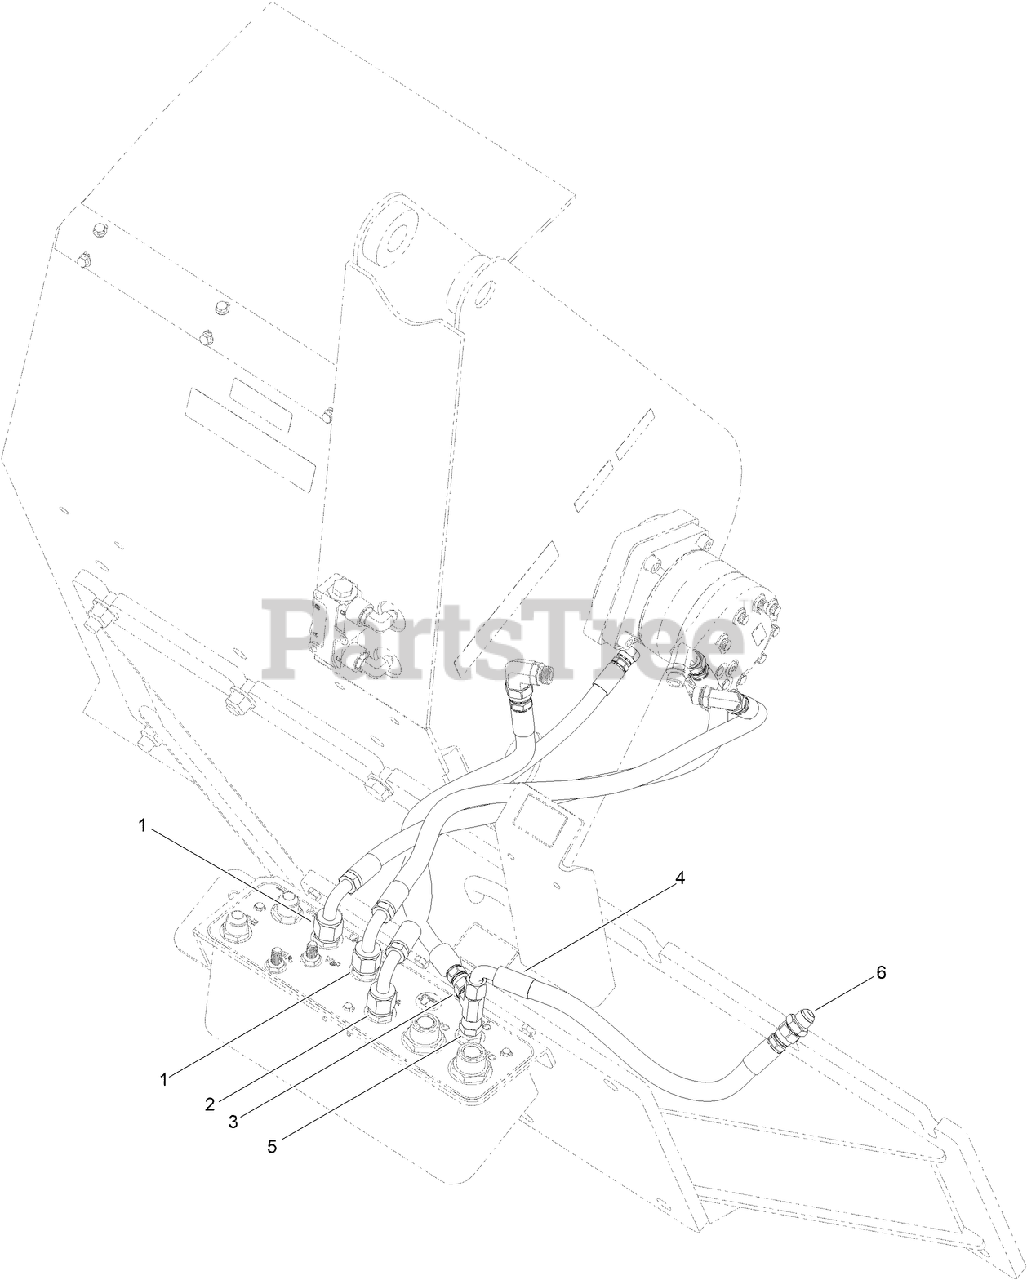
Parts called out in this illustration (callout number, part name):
1	HOSE ASM
2	HOSE ASM
3	HOSE ASM
4	HYD HOSE ASM
5	FITTING-TEE
6	FITTING-UNION
